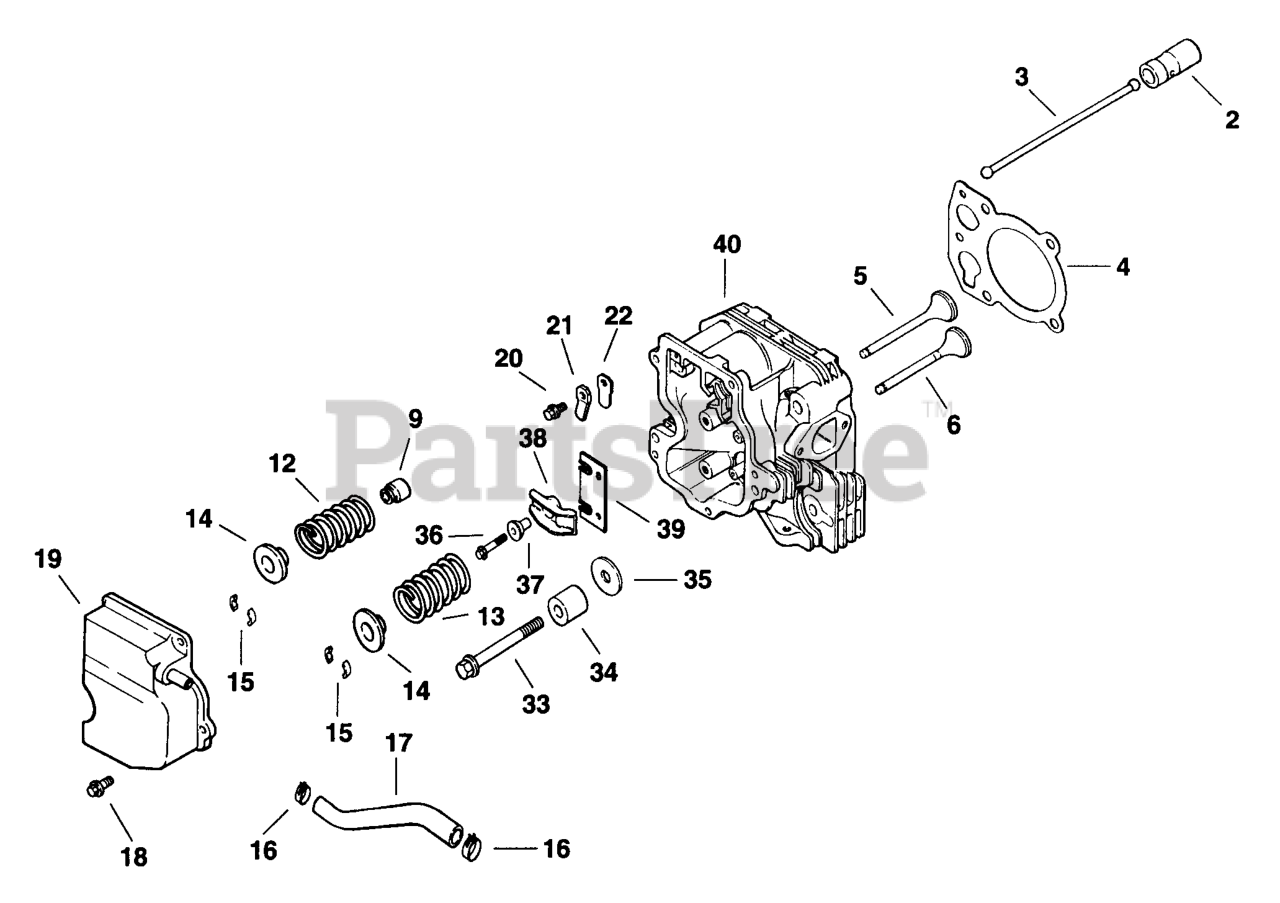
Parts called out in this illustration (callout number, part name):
2	Lifter, Valve
3	Rod, Push
4	Gasket, Cylinder Head
5	Valve, Intake (Std.)
5	Valve, Intake (.25 O.S.)
6	Valve, Exhaust (Std.)
6	Valve, Exhaust (.25 O.S.)
9	Seal, Valve Stem
12	Spring, Intake Valve
13	Spring, Exhaust Valve
14	Cap, Valve Spring
15	Kit, Retainer
16	Clamp, Hose
17	Hose, Breather
18	Screw, Hex. Flange M6x1.0x20
19	Cover, Valve W/Nipple
20	Screw, Hex. Flange M5x0.8x10
21	Retainer, Breather Reed
22	Reed, Breather
33	Screw, Hex. Flange M10x1.5x81
34	Spacer, Head Bolt Exhaust Port (17 Mm Height)
35	Washer, Plain 13/32"
36	Screw, Hex. Flange M6x1.0x34
37	Pivot, Rocker Arm
38	Arm, Rocker
39	Plate, Guide
40	Head, Cylinder
